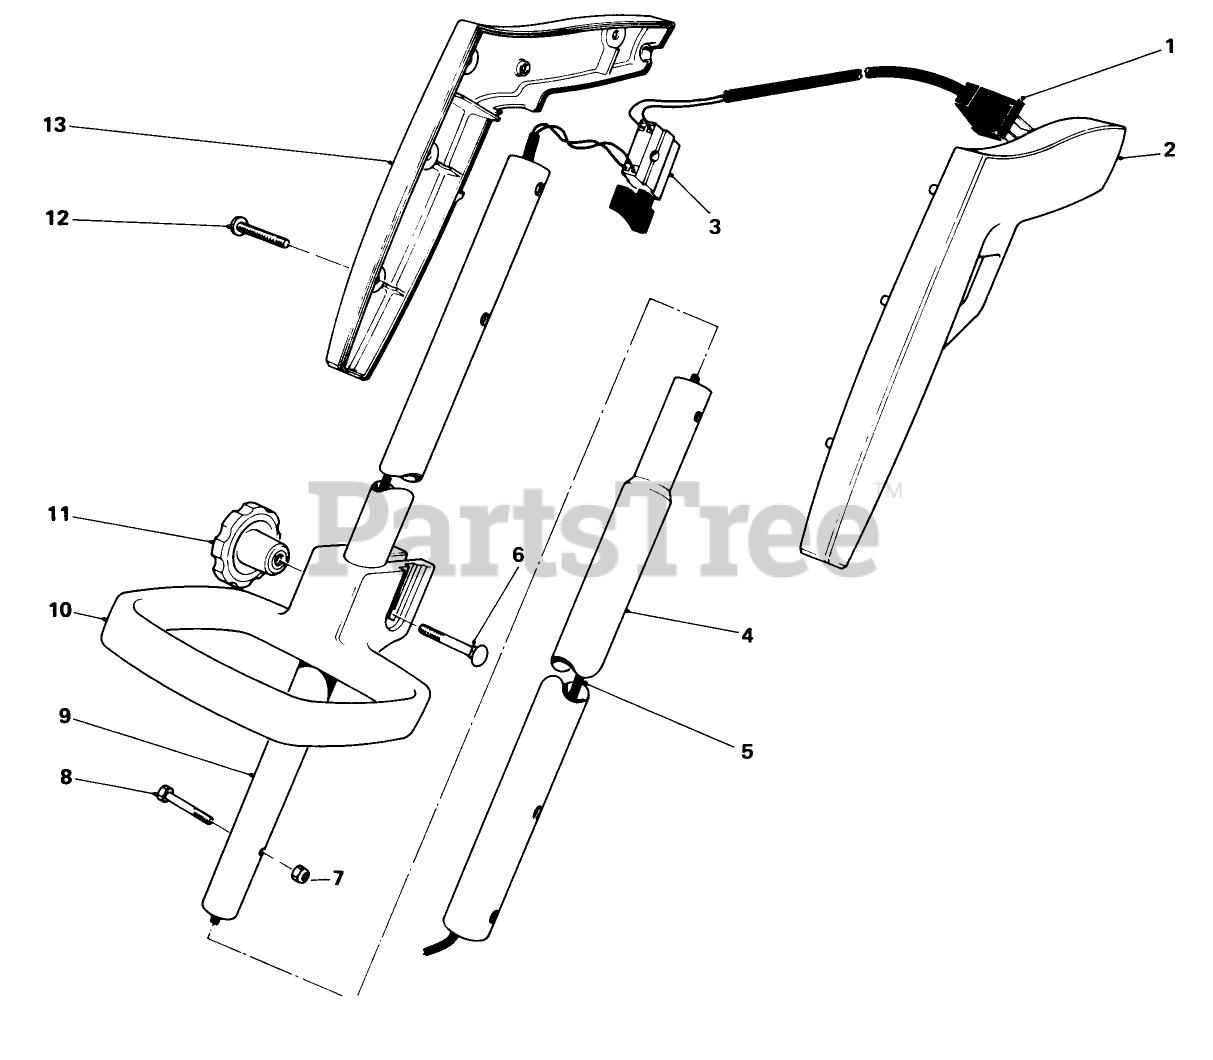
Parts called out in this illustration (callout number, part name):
3	SWITCH SINGLE SPEED
6	BOLT-CARR
7	NUT-LOCK, NI
